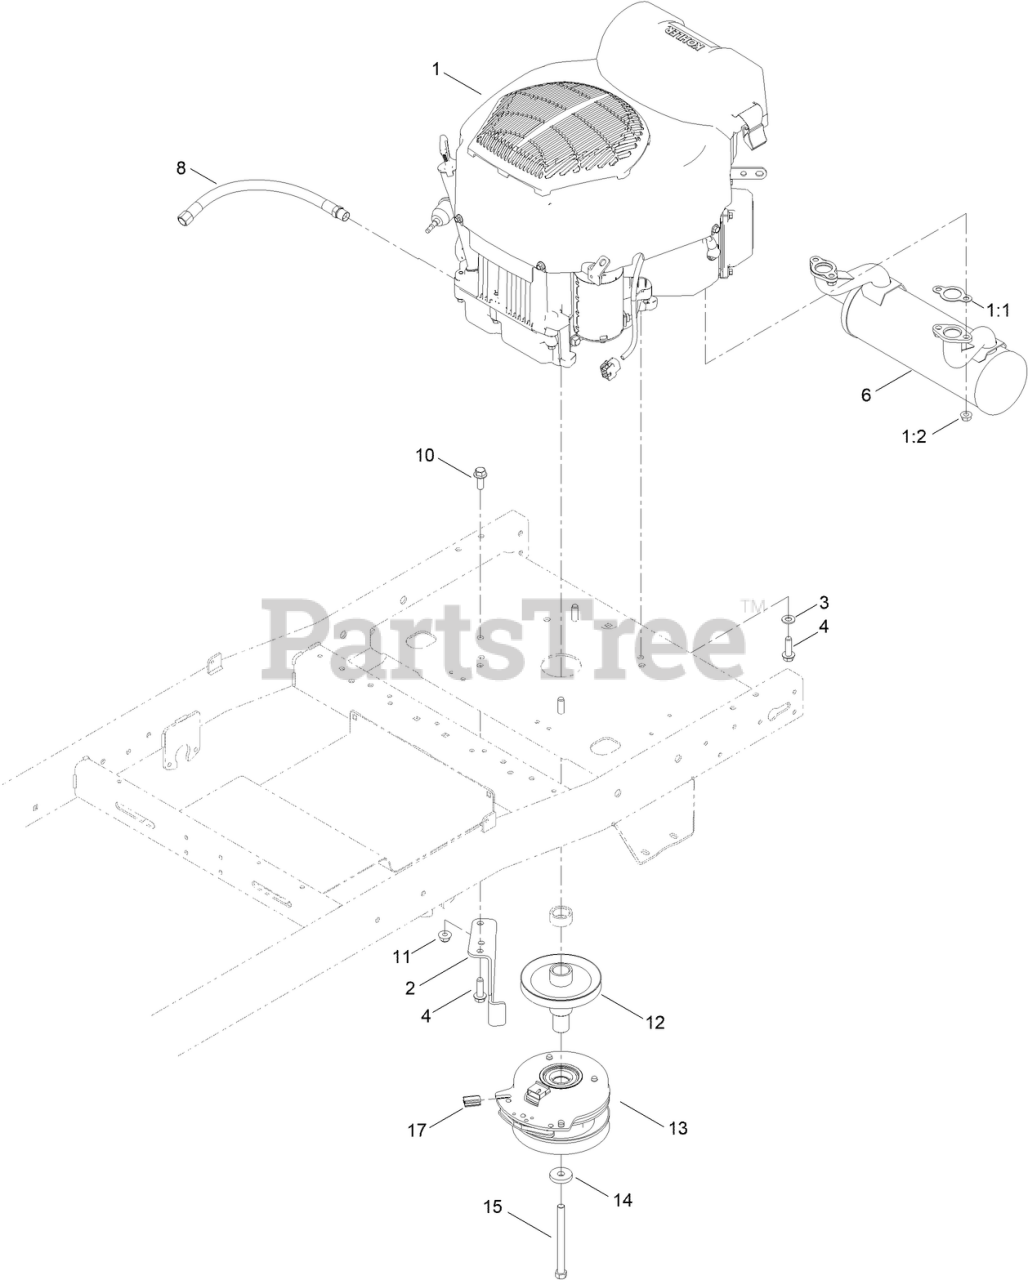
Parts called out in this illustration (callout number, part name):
1:1	GASKET-EXHAUST
2	STOP-CLUTCH (WIDE)
3	WASHER-FLAT
4	BOLT-HH
6	MUFFLER
8	TUBE-DRAIN, OIL
10	SCREW-HHF
11	NUT-HF, NI
12	PULLEY-ENGINE
13	CLUTCH-PTO
14	WASHER
15	SCREW-HH
17	ISOLATOR-CLUTCH
